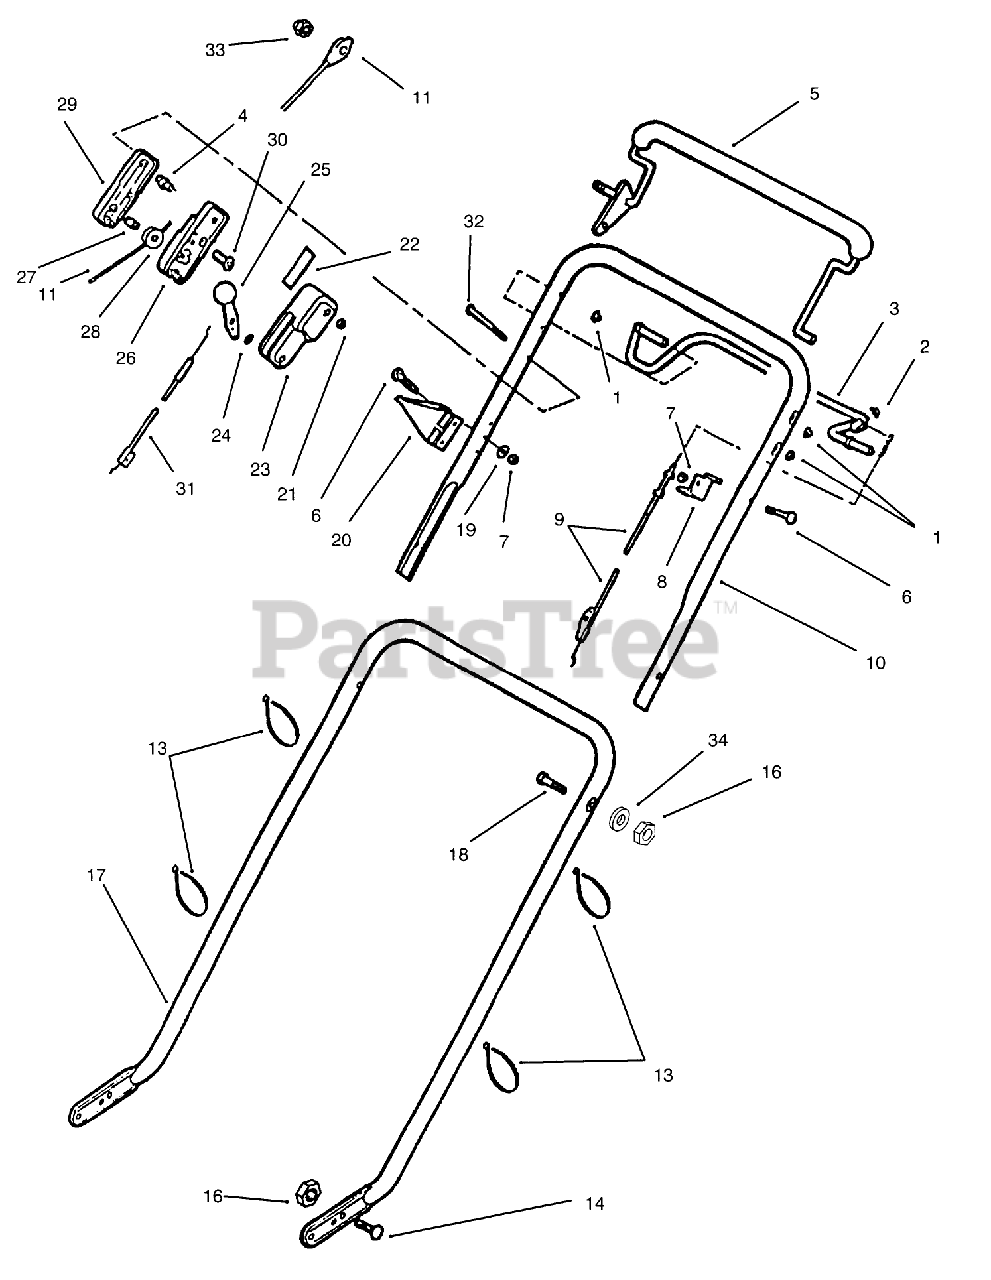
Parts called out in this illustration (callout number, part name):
5	CONTROL LEVER ARG
7	NUT-LOCK, NI
8	ANCHOR C'DUIT TRO
9	CABLE - CONTROL
11	Engine Control Cable
13	TIE-CABLE
16	NUT-LOCK, NI
18	SCREW-HH
21	NUT C/LOCK E
24	WASHER-SPRING
25	ASM - LEVER & KNOB
27	PIN SKF
28	PULLEY PL
29	OUTER CONTROL CASE
31	CABLE - THROTTLE
33	NUT ACORN
34	WASHER-CURVED
